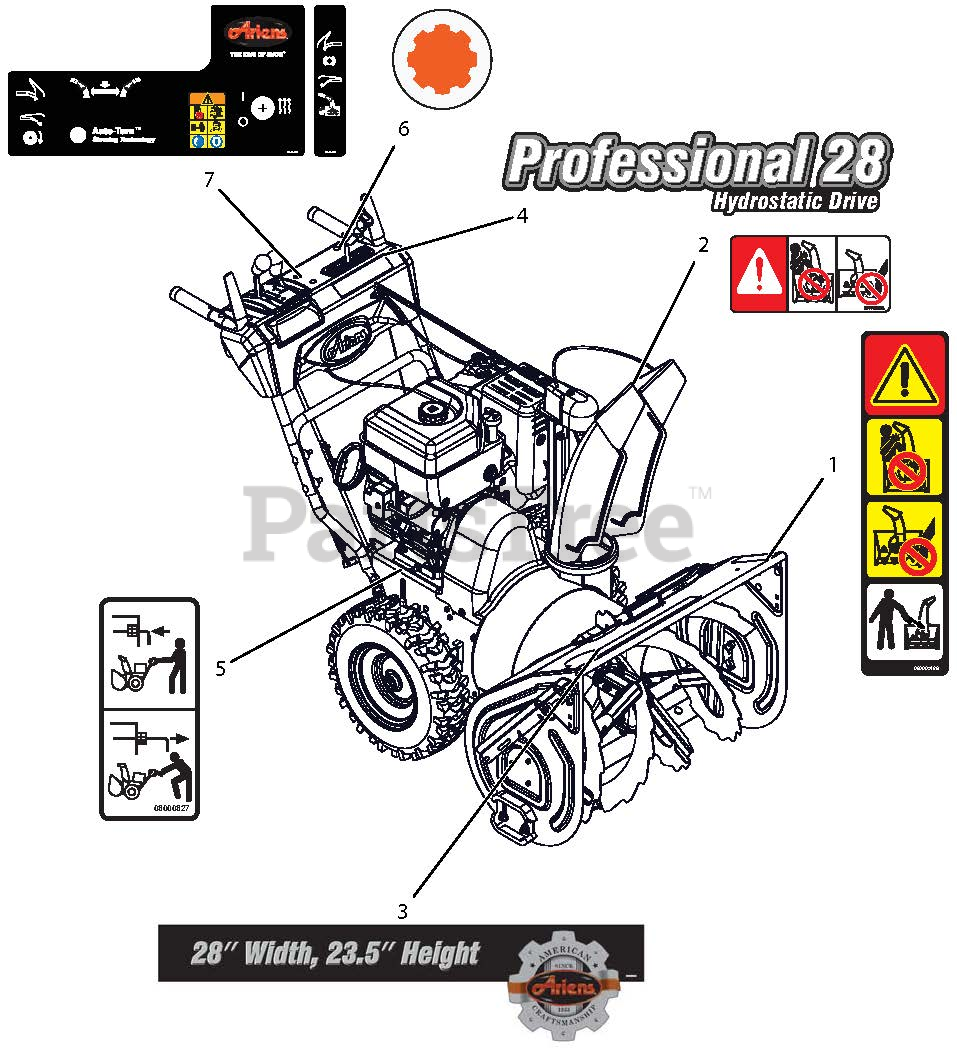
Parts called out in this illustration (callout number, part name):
1	DECAL, DANGER - ROTATING PARTS
2	DECAL, DANGER
4	DECAL, PRO HYDRO 28 DASH
5	DECAL, BYPASS
6	DECAL,AUTODIFFERENTIAL
7	DECAL,CONTROL-LRG,QT2
